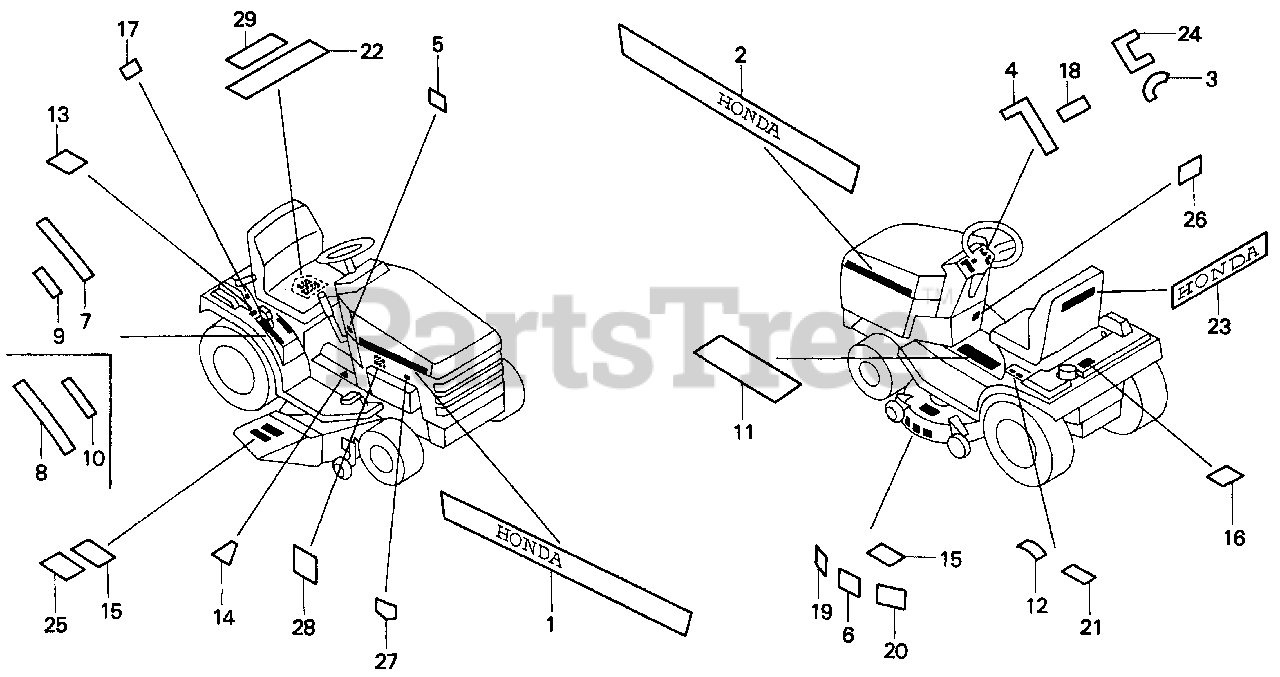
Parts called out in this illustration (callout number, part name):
1	MARK, R. STRIPE (H.S.T.)
2	MARK, L. STRIPE
3	MARK, ENGINE SWITCH INDICATION (ENGLISH)
4	MARK, THROTTLE INDICATION
5	MARK, P.T.O. INDICATION
7	MARK A, CHANGE (H.S.T.)(ENGLISH)
9	MARK B, CHANGE (H.S.T.)(ENGLISH)
11	LABEL, OPERATION (H.S.T.)
12	MARK, INDICATOR
13	MARK, PARKING OPERATION
14	MARK, BRAKE INDICATION
16	LABEL, FUEL WARNING (B)(ENGLISH)
21	MARK, HEIGHT INDICATION
22	LABEL, MANUAL (H.S.T.)
23	MARK, SEAT EMBLEM
24	MARK, LIGHT SWITCH INDICATION
26	MARK, BUZZER CAUTION (ENGLISH)
27	MARK, EX. CAUTION (A)
28	MARK, OIL CAUTION
29	LABEL, OIL RECOMMENDATION (ENGLISH)
